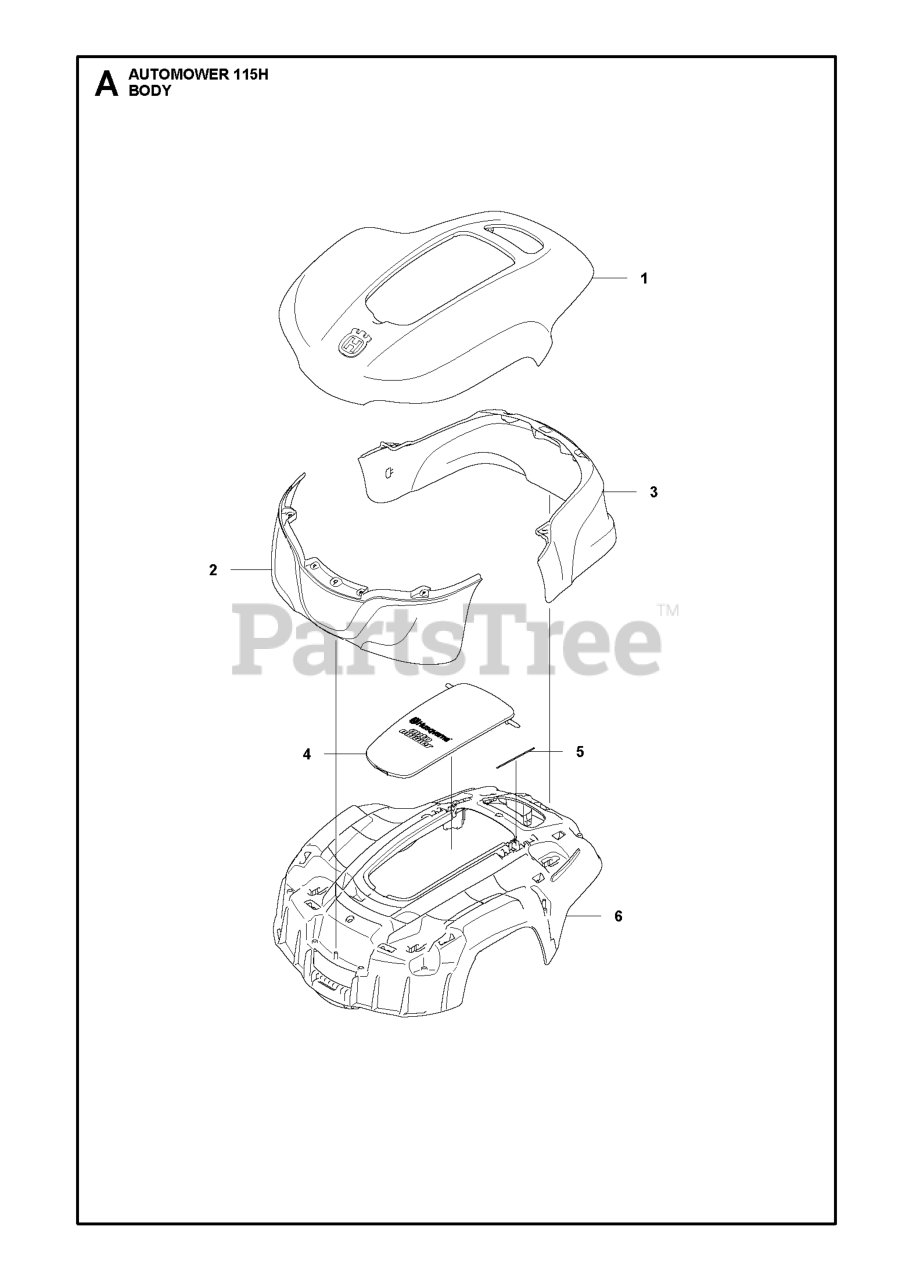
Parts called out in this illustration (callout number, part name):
2	BUMPER FRONT
3	BUMPER REAR
4	HATCH
5	SPRING D1.8 L100
6	BODY ASSY AM115H
